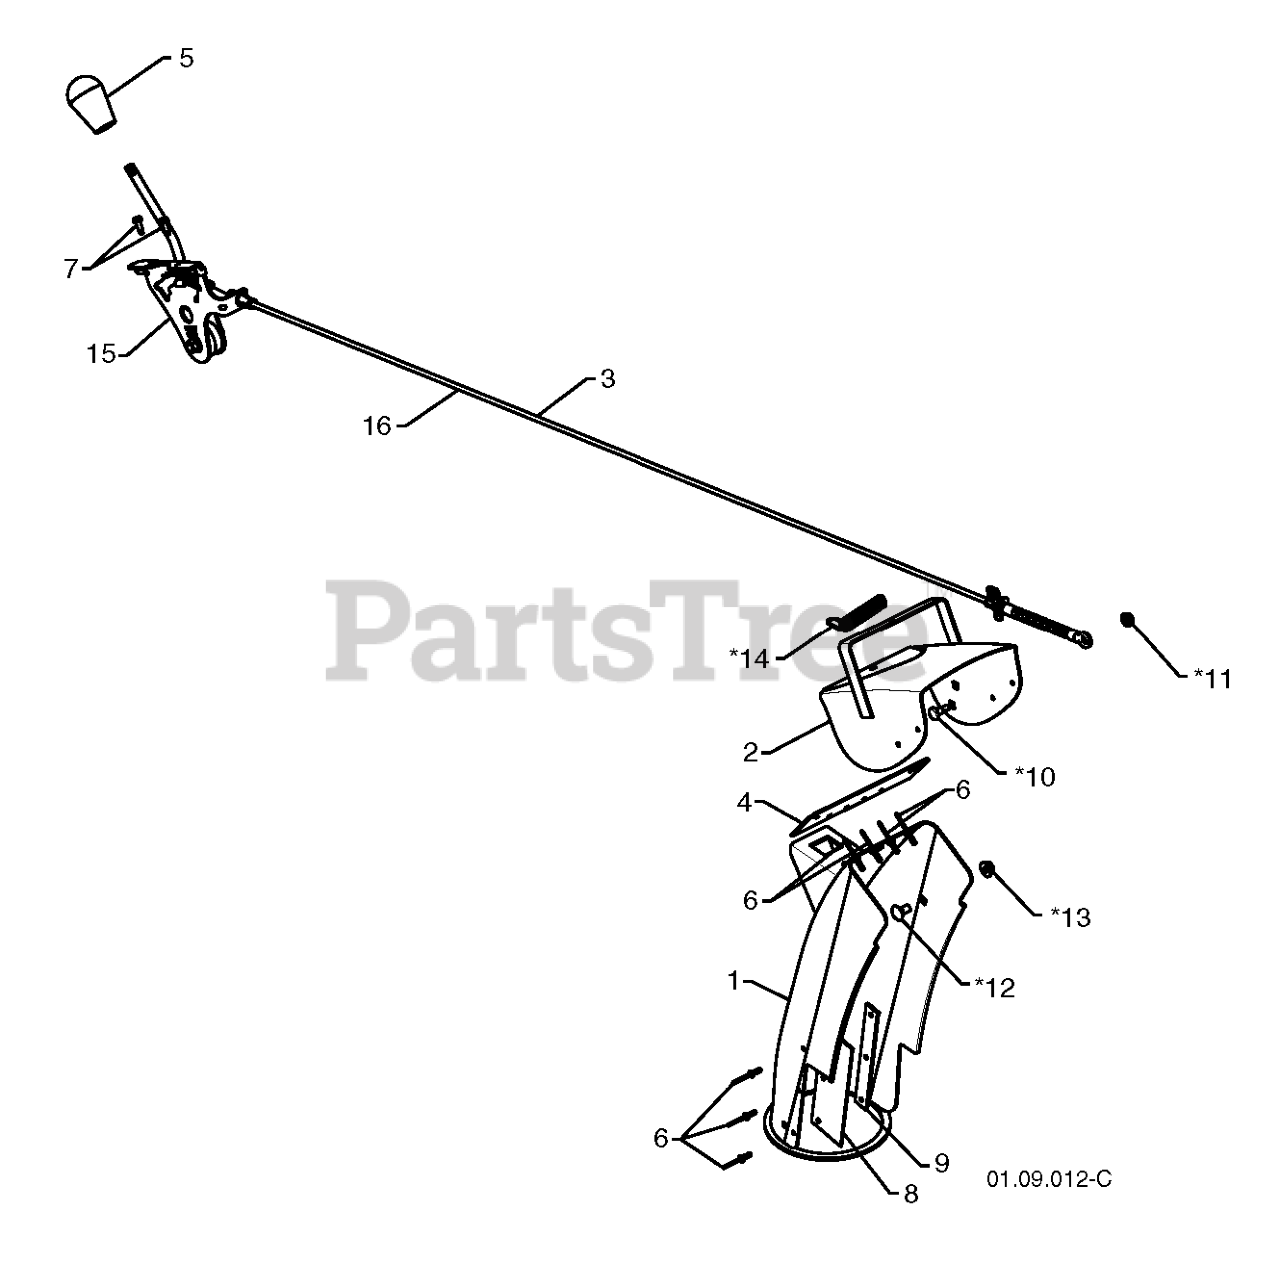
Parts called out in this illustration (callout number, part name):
1	RP CHUTE.WELDMENT.PNT.ORANGE
2	DEFLECTOR.WELDMENT.PNT.ORANGE
3	CONTROL.ASM.DEFLECTOR
4	SEAL.DEFLECTOR
5	KNOB LEVER, BLACK
6	RIVET BLIND
7	SCREW #10-24 X 5/8
8	SHIELD.SNOW.CHUTE
9	RP STRAP.SHEILD.RETAINER
10	BOLT, SHOULDER
11	NUT.HEX.FLANGE.1/4
12	BOLT
13	NUT.LOCK.5/16-18
14	SPRING.DEFLECTOR.REM.CHUTE
15	RP CNTRL.HEAD.ASSEM.DEFLECTOR
16	SERVICE.CHUTE.DEF.CBL.GRY
